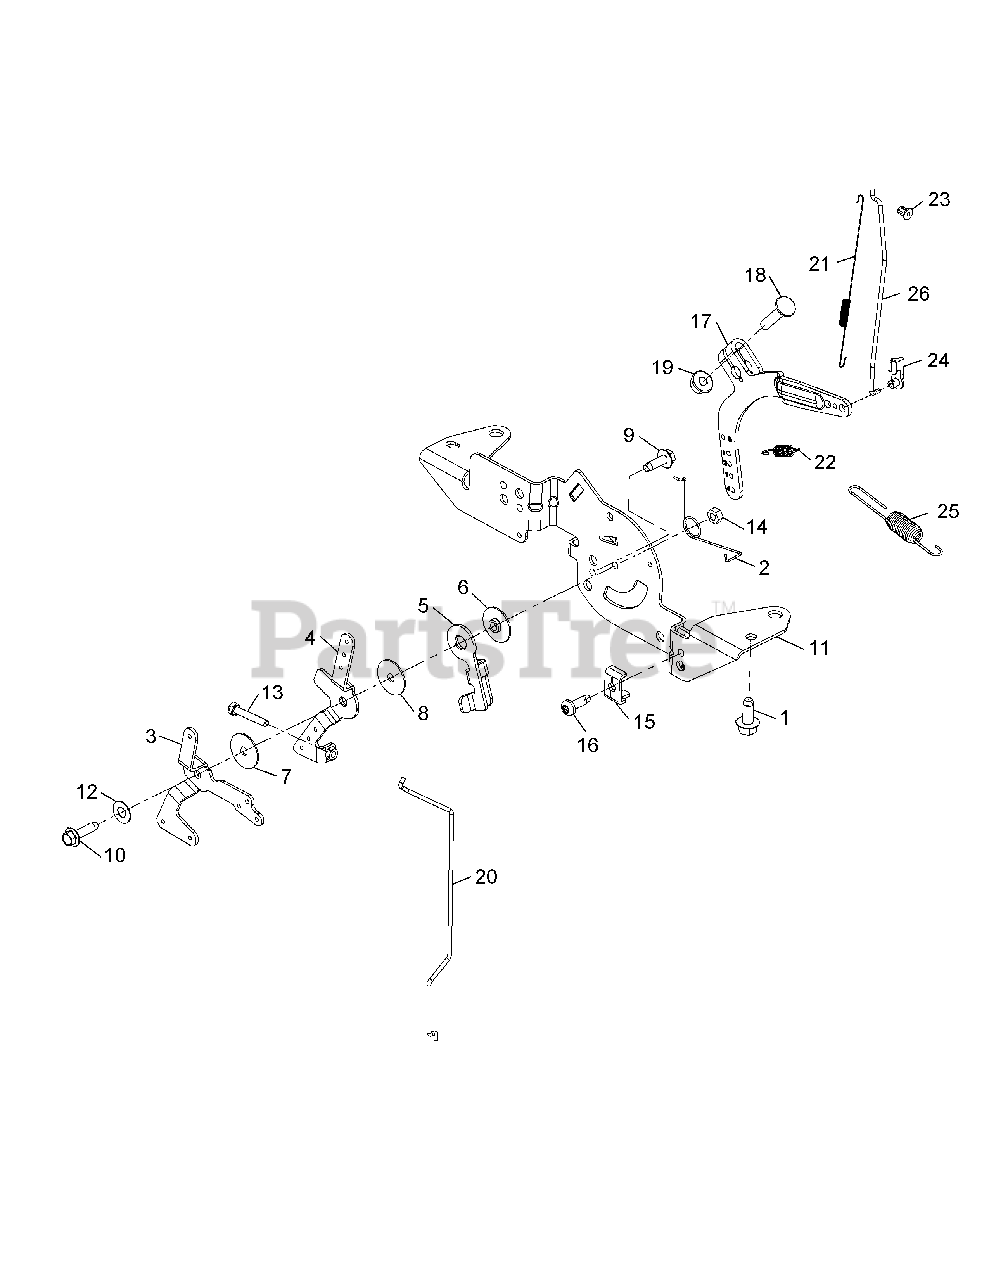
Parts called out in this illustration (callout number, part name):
1	Thread Forming Screw
2	Choke Return Spring
4	Throttle Control Lever
5	Throttle Actuator Lever
6	Control Assembly Spacer
7	Flat Washer, 5.5mm
8	Flat Washer, 5mm
9	Thread Forming Screw
10	Thread Forming Screw
11	Control Bracket
12	Spring Washer, 1/4
13	Screw, M4 x 0.7 x 25
14	Lock Nut, M5 x .8
15	Cable Clamp
16	Thread Forming Screw
17	Governor Lever
18	Bolt, M6 x 1.0 x 25
19	Flange Nut, M6 x 1.0
20	Choke Linkage
21	Linkage Spring
22	Governor Spring
23	Linkage Retaining Bushing
24	Throttle Linkage Bushing
25	Governor Spring
26	Throttle Linkage
